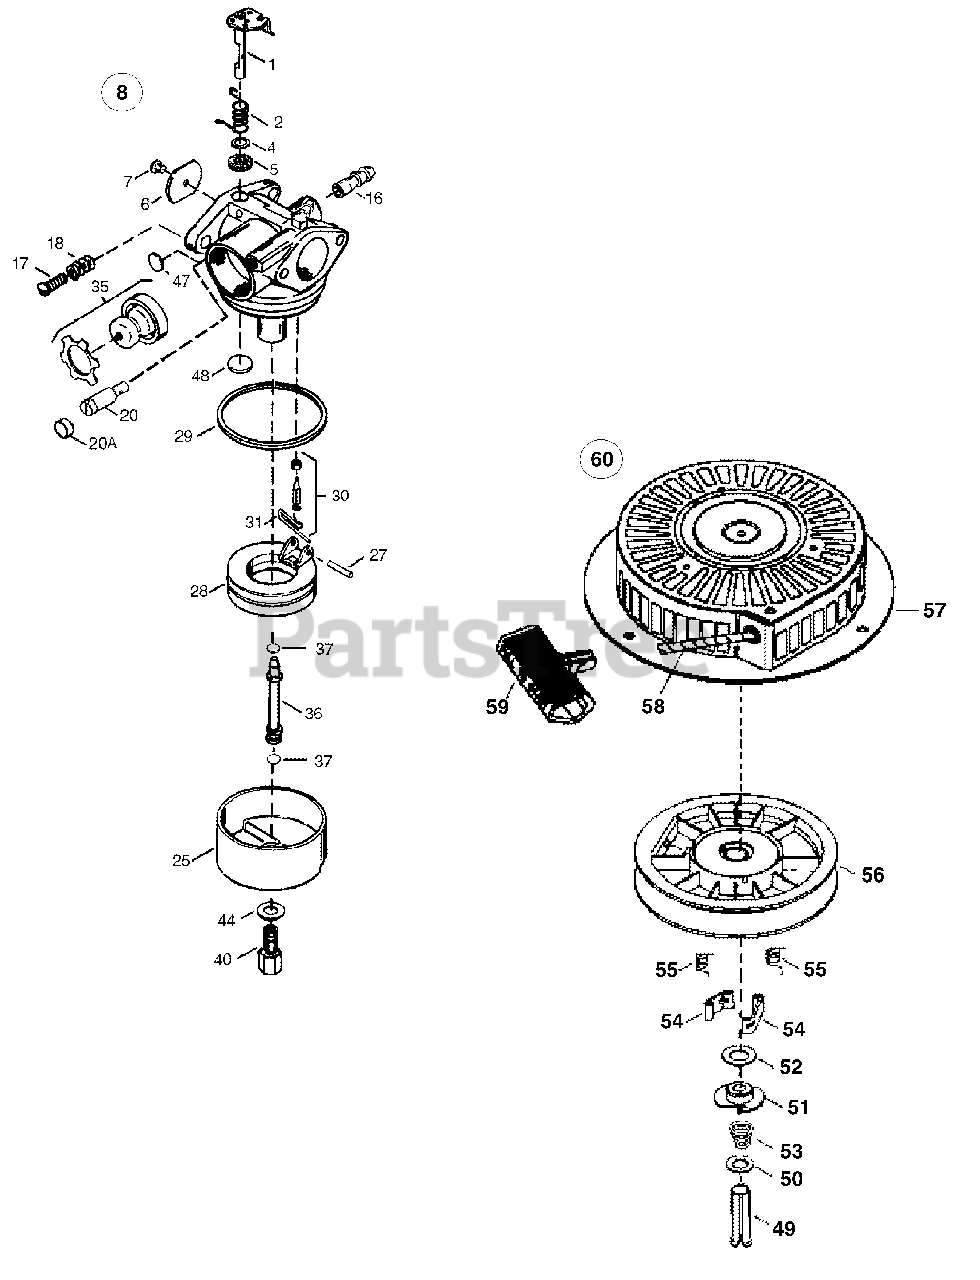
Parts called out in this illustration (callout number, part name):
1	Throttle Shaft & Lever Ass'y
2	Throttle Return Spring
4	Dust Seal Washer
5	Dust Seal (Throttle)
6	Throttle Shutter
7	Shutter Screw
8	Carburetor Assembly
16	Fuel Fitting
17	Throttle Crack/Idle Speed Screw
18	Tension Spring
20	Idle Restrictor Screw
25	Float Bowl
27	Float Shaft
28	Float
29	Float Bowl"O" Ring
30	Inlet Needle, Seat & Clip
31	Spring Clip
35	Primer Bulb/Retainer Ring
36	Main Nozzle Tube
37	Main Nozzle Tube"O" Ring
40	High Speed Bowl Nut
44	Bowl Nut Washer
47	Welch Plug, Idle Mixture Well
48	Welch Plug, Atmospheric Vent
49	Spring Pin,
53	Brake Spring
54	Starter Dog
55	Dog Spring
56	Pulley & Rewind Spring Ass'y
57	Starter Housing Ass'y
58	Starter Rope (98")
59	Starter Handle
60	Rewind Starter Ass'y
